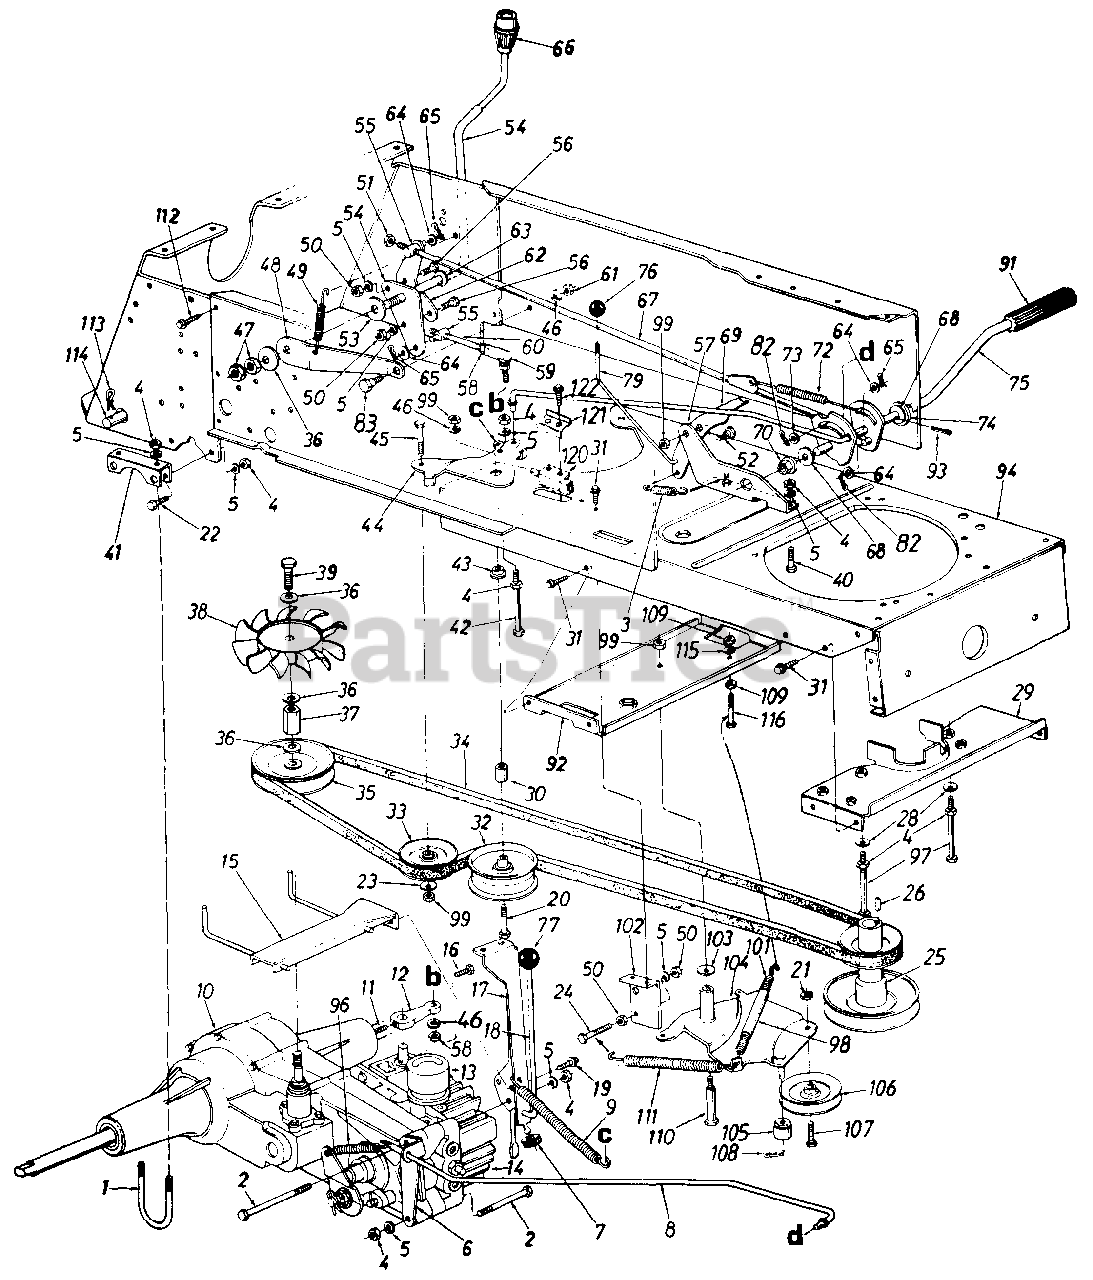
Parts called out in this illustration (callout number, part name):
1	U-Bolt 5/16-18 x 3.25" Lg.
2	Hex Patch Bolt 5/16-18 x 4.5" Lg. (Gr. 5)
3	Ext. Spring .5" O.D. x 1.55"
4	Hex Nut 5/16-18 Thd.
5	L-Wash. 5/16" I.D.
6	Brake Rod Guide Brkt.
7	Rubber Wash. .33" I.D. x .87"
8	Brake Rod
9	Ext. Spring .62" O.D. x 6.12" Lg.
10	Transaxle
11	Set Screw 5/16-24 x .38" Lg.
12	Pintle Shift Lever
13	Reservoir
14	Hydrostatic Pump
15	Belt Guard Ass'y.
16	Hex Bolt 5/16-18 x 4.5" Lg. (Gr. 5)
17	Transaxle Torque Bracket
18	Transaxle Control Rod
19	Hex Wash. Hd. B-Tap Scr. 5/16-18
20	Hex Bolt 3/8-16 x 2.75" Lg.
21	Hex Cent. Lock Nut 3/8-16 Thd.
22	Hex Bolt 5/16-18 x .75" Lg. (Gr. 5)
23	Fl-Wash. .385" I.D. x .87" O.D.
24	Hex Bolt 5/16-24 x 1.75" Lg.
25	Engine Pulley
26	Sq. Key 1/4 x 1.5" Lg.
28	Bell-Wash. .345" I.D. x .88" O.D.
29	Belt Keeper Brkt. Ass'y.
30	Spacer .375" I.D. x .75" Lg.
31	Hex Wash. Hd. TT-Tap Scr. 1/4-20 x .5" Lg.
32	Fl-Idler Pulley 3.25" Dia.
33	V-Belt Idler
34	V-Belt
35	Transmission Pulley 4.25" O.D.
36	Bell-Wash. .56" I.D. x 1.5"
37	Fan Adapter Nut 9/16-18 Thd.
39	Hex Bolt 9/16-18 x .5" Lg.
40	Hex Bolt 5/16-18 x .75" Lg.
41	Transaxle Mtg. Bracket
42	Hex Bolt 5/16-18 x 2.75" Lg.
43	Shld. Spacer.625" I.D.
44	Clutch Idler Bracket
45	Hex Bolt 3/8-16 x 1.5" Lg.
46	L-Wash. 3/8" I.D.
47	Hex Jam Nut 1/2-20 Thd.
48	Speed Control Rod Torque Brkt.
49	Ext. Spring 2.5" Lg.
50	Hex Nut 5/16-24 Thd.
51	Hex Jam Nut 3/8-24 Thd.
52	Shld. Bolt .50" Dia. x .170"
53	Fiber Washer .54" I.D. x 1.75"
54	Speed Control Handle Ass'y.
55	Ferrule 3/8-24 Thd.
56	Hex Bolt 5/16-24 x .62" Lg.
57	Foot Pedal Mtg. Brkt.
58	Hex Nut 3/8-24 Thd.
59	Ball Joint Ass'y.
60	Control Rod 3/8-24 x 3.75" Lg.
61	Hex Nut 3/8-16 Thd.
62	Speed Selector Handle Brkt.
63	Fl-Wash. .531" I.D. x 1.25" O.D.
64	Fl-Wash. .385" I.D. x .62" O.D.
65	Internal Cotter Pin
66	Shift Knob
67	Neutral Return Rod
68	Fl-Wash. .64" I.D. x 1.24" O.D.
69	Parking Brake Lock Brkt.
70	Hex Flange Brg. .634" Dia.
72	Extension Spring 8" Lg.
73	Fl-Wash. .344" I.D. x .62" O.D.
74	Flange Bearing w/Flats
75	Foot Pedal Ass'y.
76	Ball Knob Brake
77	Ball Knob 1/4-20 Thd.
79	Parking Brake Link
82	Cotter Pin 3/32" Dia. x 1.0" Lg.
83	Shld. Bolt .5" Dia. x .212"
91	Foot Pad
92	Deck Idler Support Brkt.
93	Cotter Pin 1/8" Dia.
94	Lower Frame
96	Ext. Spring 3.675" Lg.
97	Hex Bolt 5/16-18 x 5-1/4" Lg.
98	Convoluted Conduit 4" Lg.
99	Hex Cent. L-Nut 3/8-16 Thd.
101	Extension Spring 6.37" Lg.
102	Parking Brake Mtg. Brkt.
103	Bell-Wash. .380" I.D. x .88" O.D.
104	Idler Brkt. Deck Ass'y.
105	Spacer
106	V-Belt Idler
107	Hex Bolt 3/8-24 x 1.5" Lg.
108	Internal Cotter Pin
109	Hex Nut 1/4-20 Thd.
110	Shld. Bolt .498" Dia. x 2.05"
111	Ext. Spring 4.0" Lg.
112	Hex Wash. AB-Tap Scr. 5/16 x .75" Lg.
113	Hitch Pin Clip
114	Hitch Rod
115	L-Wash. 1/4" I.D.
116	Hex Bolt 1/4-20 x 2" Lg.
120	Safety Switch
121	Switch Plate
122	Torx Nd. Mach. B-Tap Scr.
